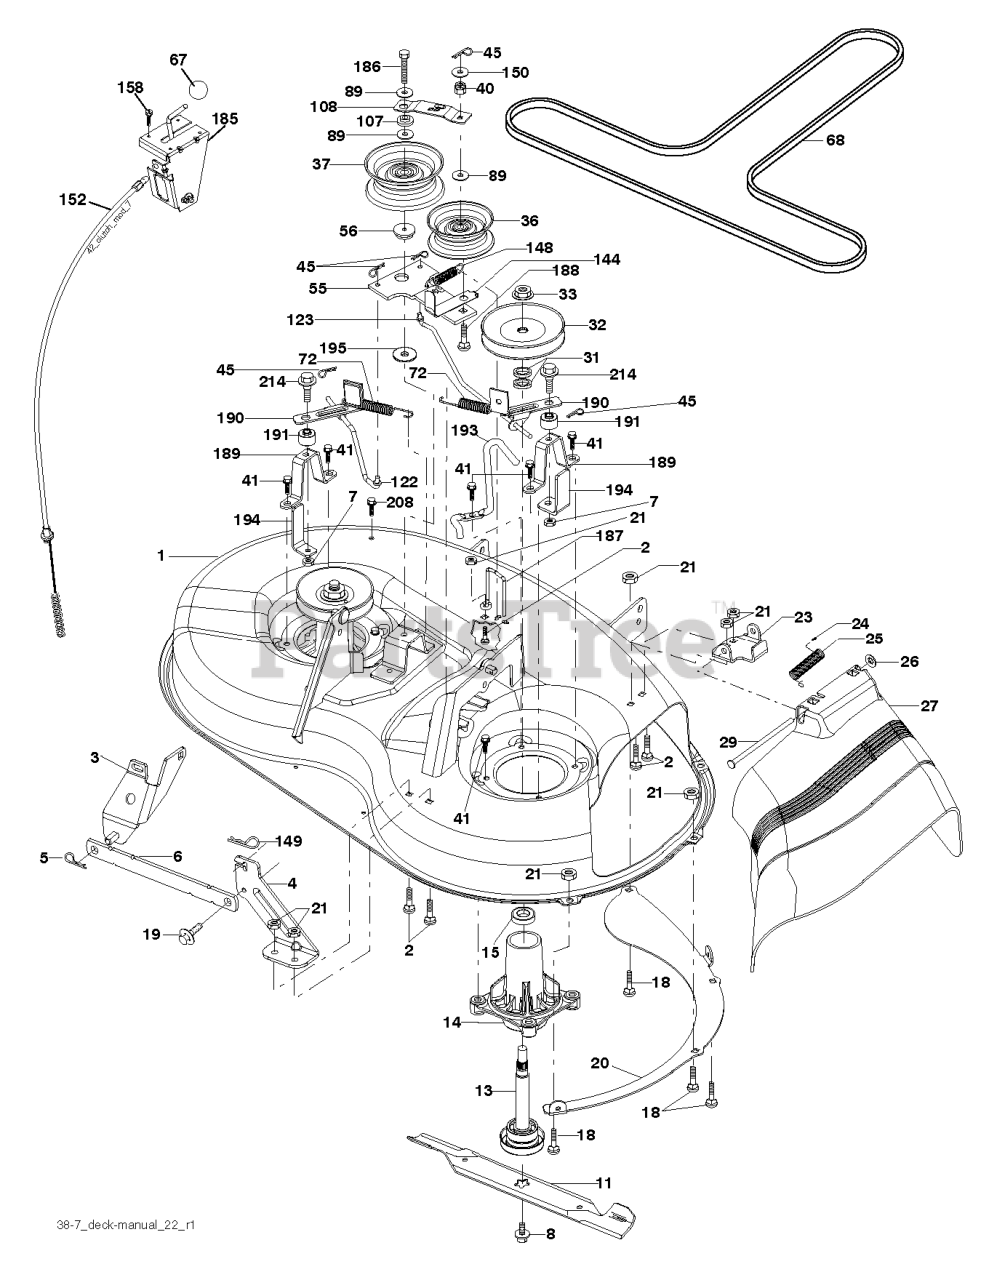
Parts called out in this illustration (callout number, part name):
1	DECK SVCX1 38/94 192556X431
2	RP BOLT 5/16-18 X3/4 ZN/YEL GR
3	BRKT ASM SWAY BAR
4	BRACKET DECK SWAY BAR 38"/42"
5	RETAINER-SPRNG RB
6	BAR SWAY DECK
7	NUT.71038.31-18.HEX.NYLOCK
8	BOLT.WASHER.ASM.7/16-2
11	BLADE 38" PREMIUM
13	SHAFT.ASM.MDRL.N/GREASE.38
14	RP.HOUSING.MANDREL.4PT.
18	BOLT
19	BOLT SHD 5/16-18
20	BAFFLE.VORTEX.FRONT.38"
21	LOCKNUT
23	BRKT.DEFLECTOR.38"2005+
24	CAP-SLEEVE LT
25	SPRING.TORSION.DEFLECT
26	NUT PUSH M
27	SHIELD.DEFLECTOR.MWR.38-7/97CM
29	ROD.HINGE
31	WASHER.SPACER.MANDREL
32	PULLEY MANDREL
33	NUT.FLANGE.LOCK.TOP
36	FLAT IDLER PULLEY
37	PULLEY.IDLER.FLAT.UNPLATED
41	BOLT.HEX.WASHR.HED.313-18X1.19
45	RETAINER M
55	IDLER ARM
56	SPACER.RETAINER.MOWER
67	KNOB T (3/8 HOLE)
68	V-BELT.MOWER.38"2005+
72	SPRING.BRAKE.RETURN.38"
89	WASHER
107	SPACER.IDLER.ARM
108	STIFFENER.IDLER.ARM
122	LINK.BRAKE.38"LEFT.2007
123	LINK.BRAKE.38"RIGHT
144	KEEPER BELT
148	IDLER RETURN SPRING
149	SPRING.RETAINER.YELLOW.ZINC
150	WASHER LT
152	CABLE.CLUTCH.38".SERVICE
158	SCREW
185	HEAD ASM. CABLE CLUTCH
186	SCREW.HXWSH.3/8
187	KEEPER BELT
188	BOLT, CARRIAGE IDLER
189	STAND, BRAKE
190	ARM, BRAKE
191	BRAKE.SPACER.38".DECK
193	KEEPER BELT RH MANDREL
194	GUARD BRAKE
195	WASHER 12/32X2X10GA
208	SCREW 3/8-16X1/2
214	BOLT/WASHER ASM 5/16-18
